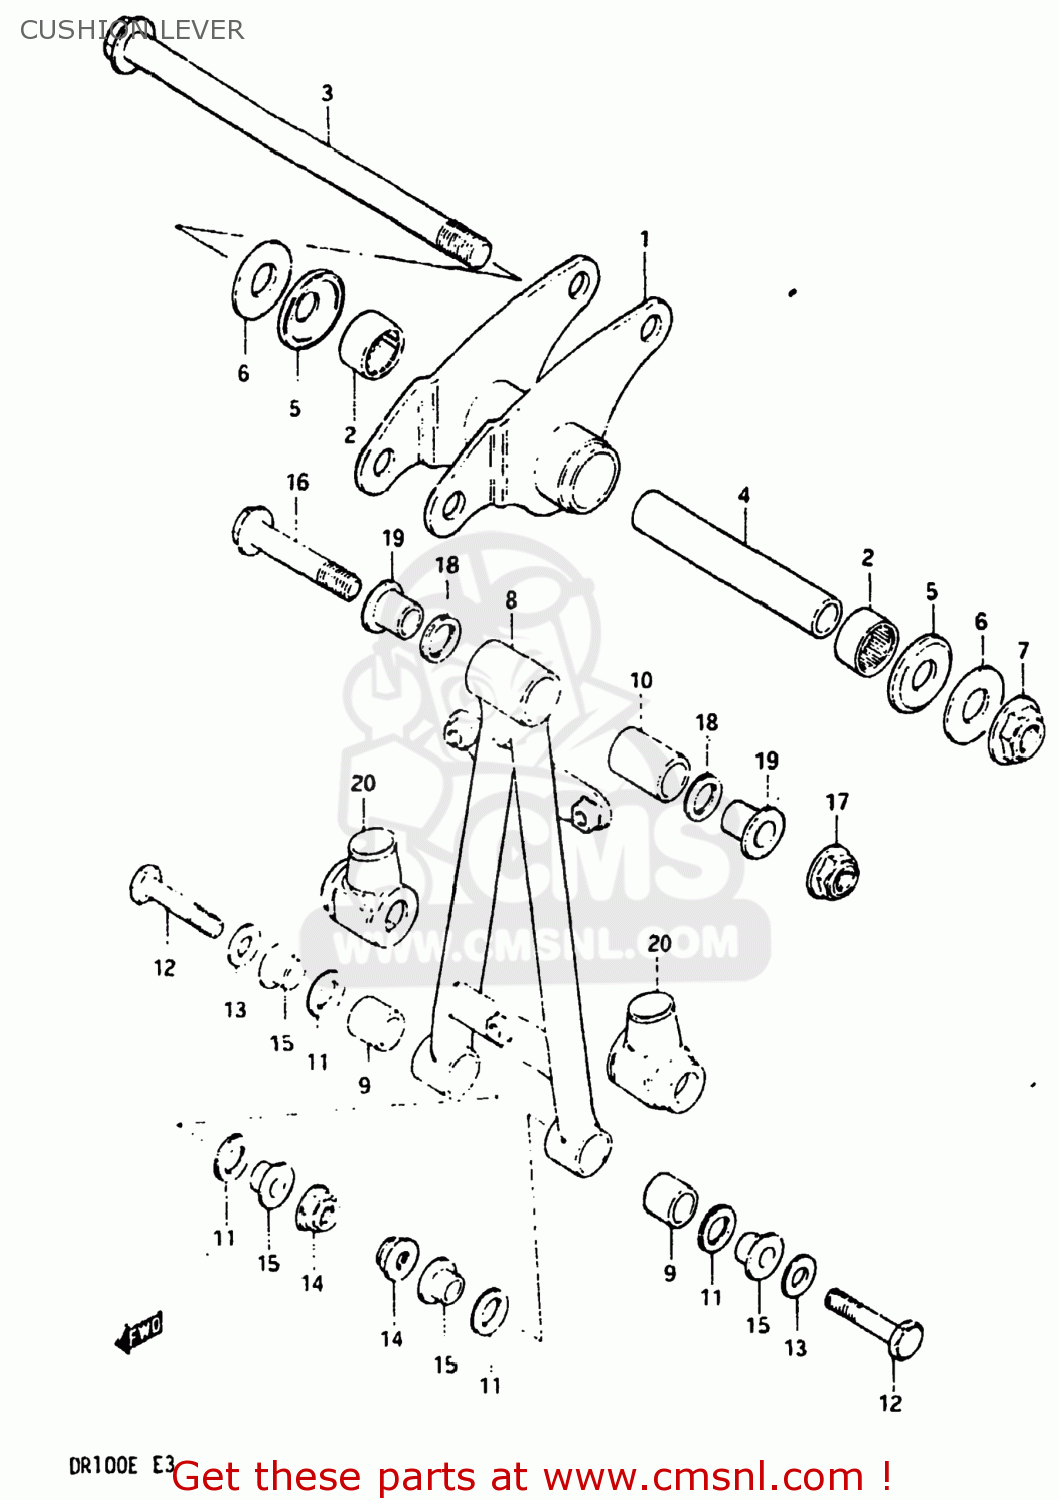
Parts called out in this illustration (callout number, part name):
1	LEVER SET,REAR CUSHION
2	BEARING(17X25X20)
3	SHAFT,REAR CUSHION LEVER
4	SPACER,REAR CUSHION LEVER
5	DUST SEAL,REAR CUSHION,LEFT
6	WASHER
7	NUT 12MM
8	ROD SET,REAR CUSHION LEVER
9	BUSHING
10	BUSH,UPPER
11	DUST SEAL,RR CUSHION LOD LWR
12	BOLT,REAR CUSHION ROD
13	WASHER
14	NUT
15	SPACER,RR CUSHION ROD LWR
16	BOLT(10X65)
17	NUT
18	DUST SEAL,LEVER CUSHION UNIT
19	SPACER,RR CUSHION ROD UPR
20	BOOT,REAR CUSHION ROD,LOWER
